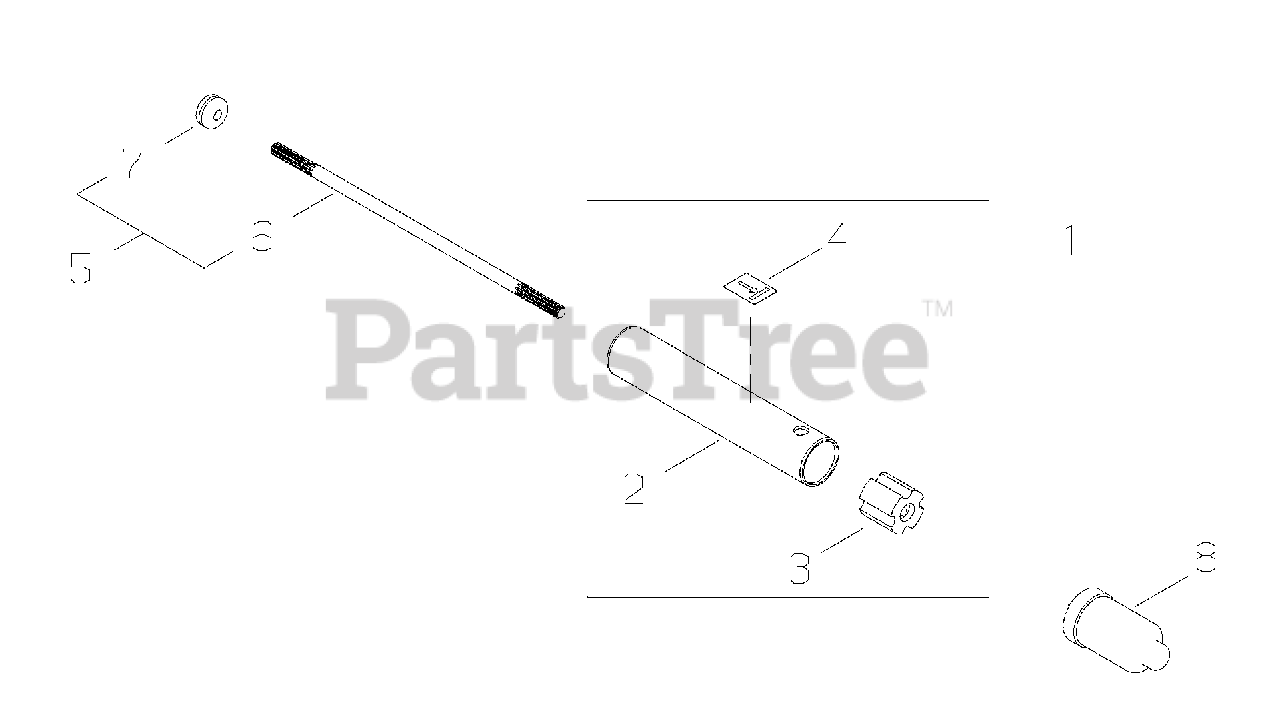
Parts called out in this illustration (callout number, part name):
1	MAIN PIPE ASSY
2	PIPE, MAIN
3	BUSHING
4	LABEL, INSTRUCTION
5	MAINSHAFT ASSY
6	MAINSHAFT
7	GROMMET
8	CAP
